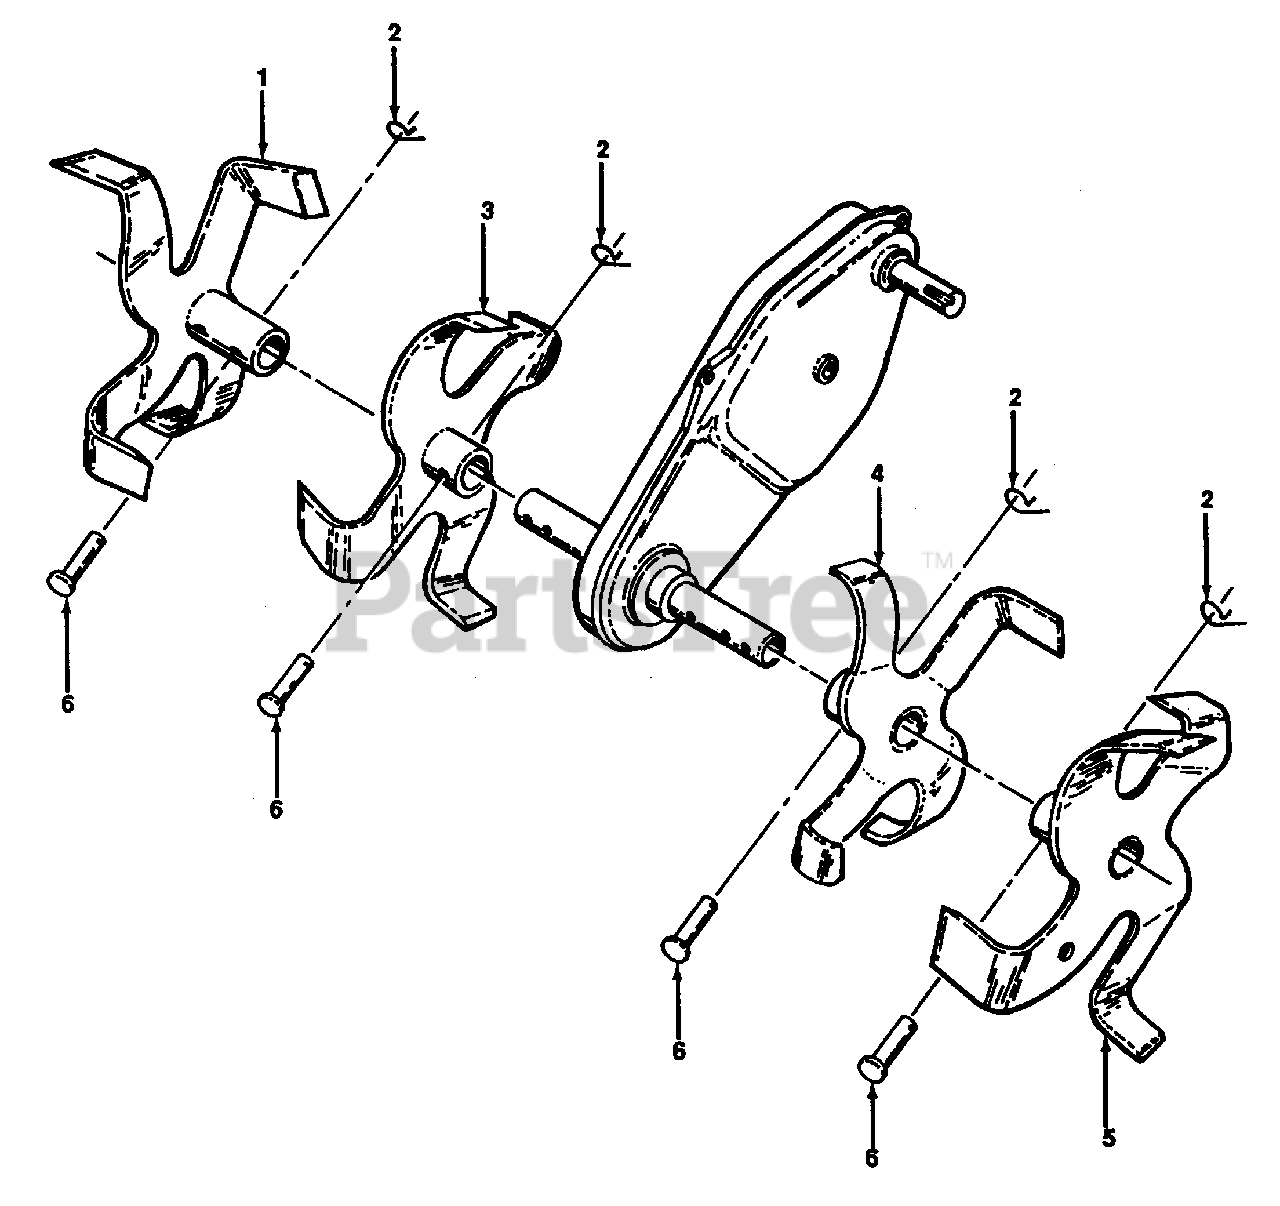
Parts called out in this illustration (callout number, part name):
1	Tine, Outer, R.H. (AYP part number)
2	Clip, Hairpin (AYP part number)
3	Tine, Inner, R.H. (AYP part number)
4	Tine, Inner, L.H. (AYP part number)
5	Tine, Outer, L.H. (AYP part number)
6	Pin, Clevis
